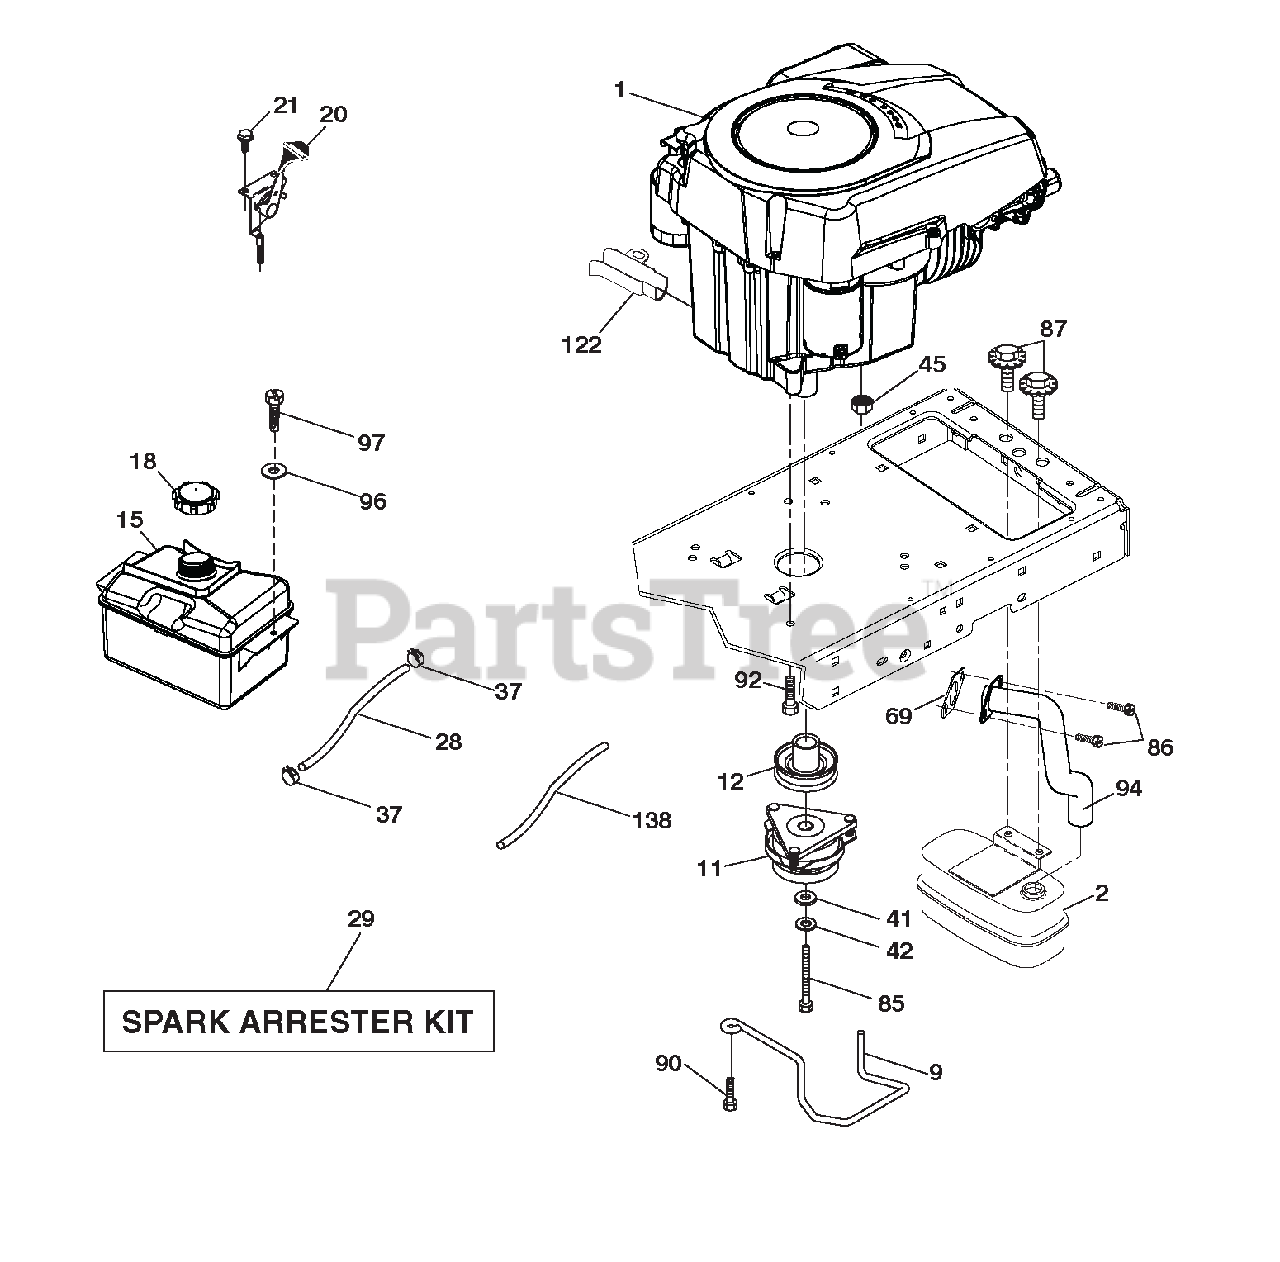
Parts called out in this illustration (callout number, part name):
1	ENGINE KOHL MODEL NO. SV530-3224 (581497201)(ORDER PARTS FROM ENGINE MANUFACTURER.)
2	MUFFLER.SINGLE.CYL.KOHL.COURAG
9	KEEPER BELT ENGINE
11	CLUTCH OGURA
12	PULLEY. ENGINE. 1" CRK.
15	TANK FUEL
18	CAP FUEL
20	CONTROL THROTTLE/CHOKE
28	LINE.FUEL.22"FRONT.EMIS.CA.LP
29	KIT.SPARK ARRESTOR(392390 B&S)
37	CLAMP.HOSE.BLK.
41	WASHER.1-1/2 ODX15/32 IDX.250
42	WASHER.LOCK.HVY HLCL.SPR.7/16
45	Nut, Keps Hex 1/4-20 unc
69	GASKET.KOHLER.SV.I.
85	BOLT.HEX.7/16-20X4XGR5-1.5THR.
86	SCREW.SOCKET HD.5/16-18 X .75
87	BOLT.5/16-18UNCX3/4 W/SEMS.BLK
90	SCREW.3/8-16X1.SMGML.TAP/R.BLK
92	SCREW.3/8-16 X 1.SMGML.TAP/R
94	TUBE.EXHAUST.KOHL.COURAGE
96	WASHER.9/32 X 7/8 X 16GA.
97	SCREW.HEXWSH.THDROL.1/4-20X3/4
122	Extension Drain Oil
138	PURGE.LINE.CARB
